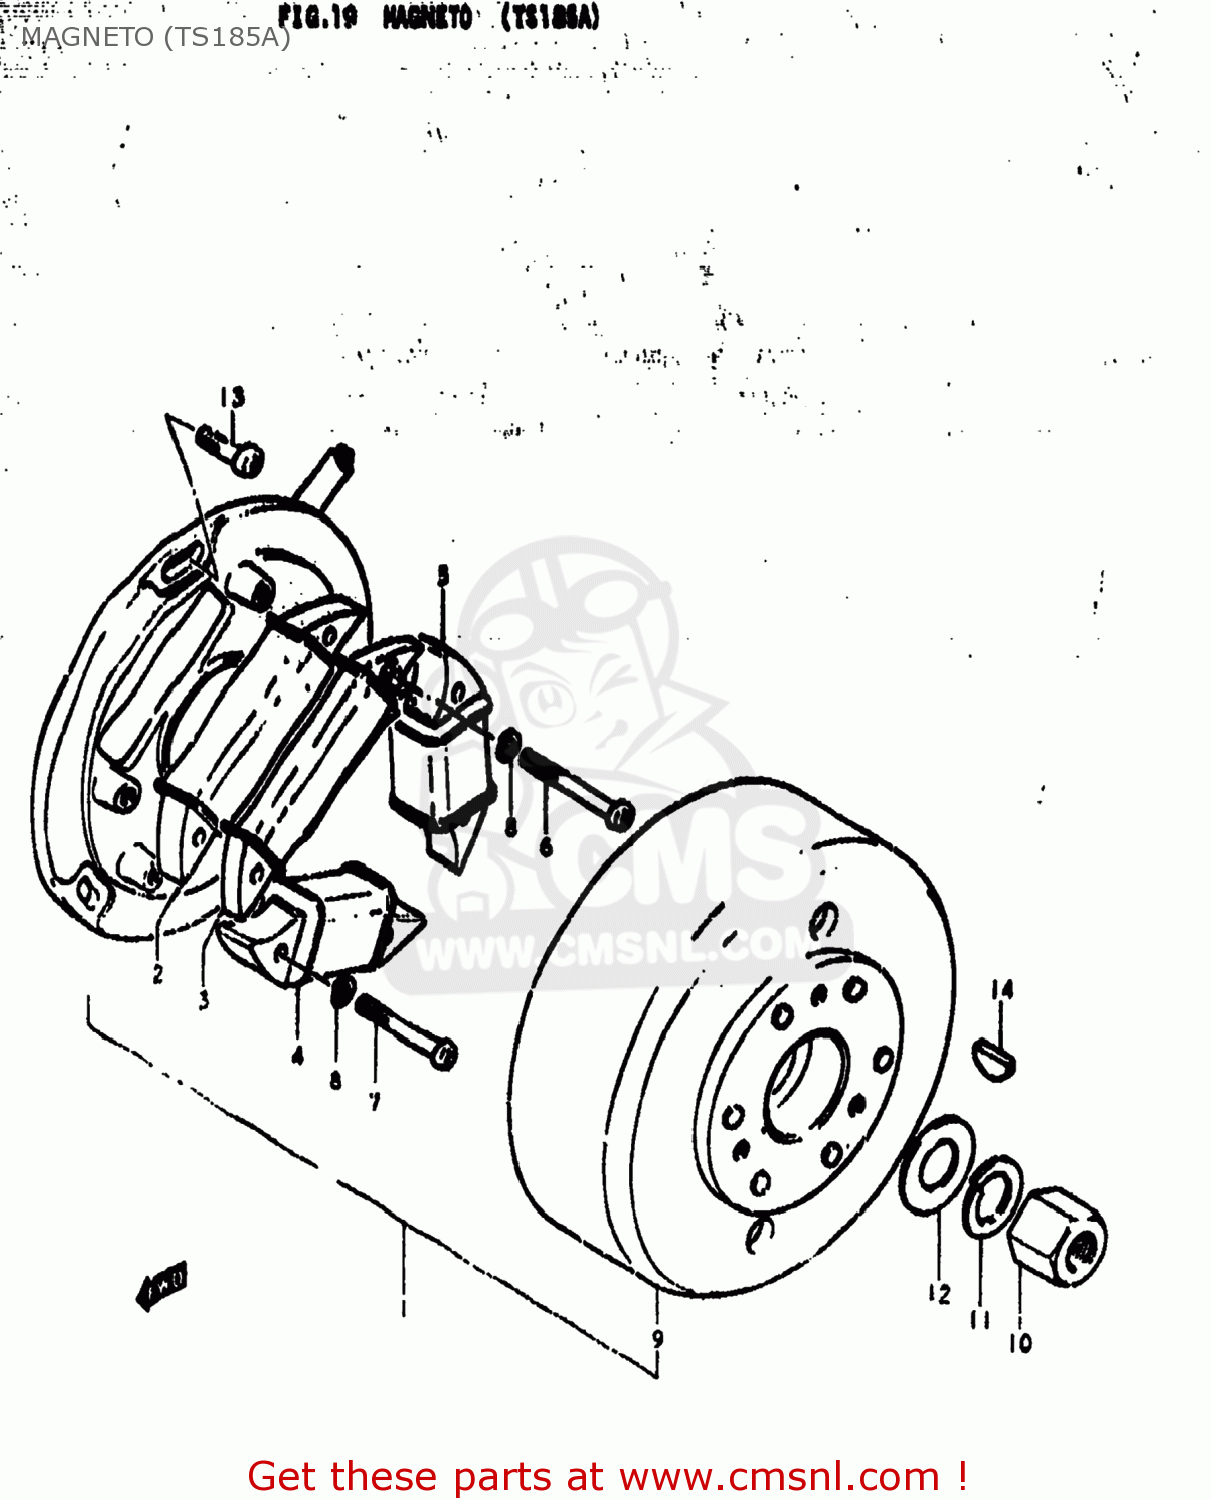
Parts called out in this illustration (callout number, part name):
1	MAGNETO ASSEMBLY
2	COIL
3	COIL,PULSER
4	COIL
5	COIL,CHARGE
6	SCREW 5X35
7	SCREW
8	LOCK WASHER
9	ROTOR,FLYWHEEL
10	NUT
11	LOCK WASHER
12	WASHER(14X27X3)
13	SCREW(5X14)
14	KEY 4MM
